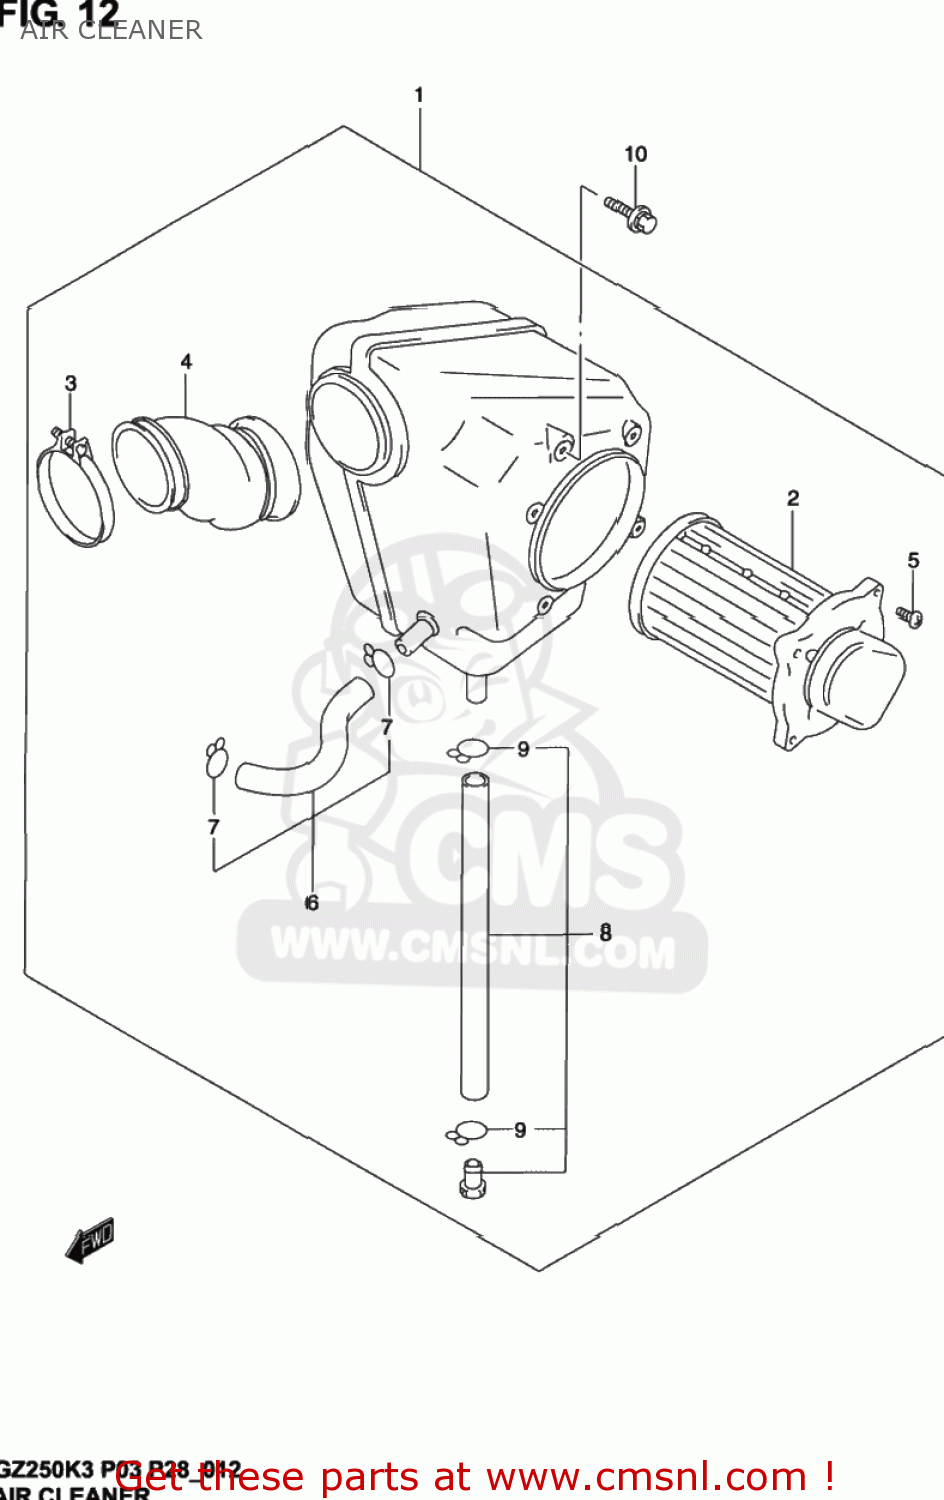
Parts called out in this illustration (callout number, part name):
1	CLEANER ASSY,AIR
2	FILTER,AIR CLEANER
3	CLAMP
4	TUBE,OUTLET
5	SCREW
6	TUBE,BREATHER
7	CLIP
8	TUBE,DRAIN
9	CLIP
10	BOLT
